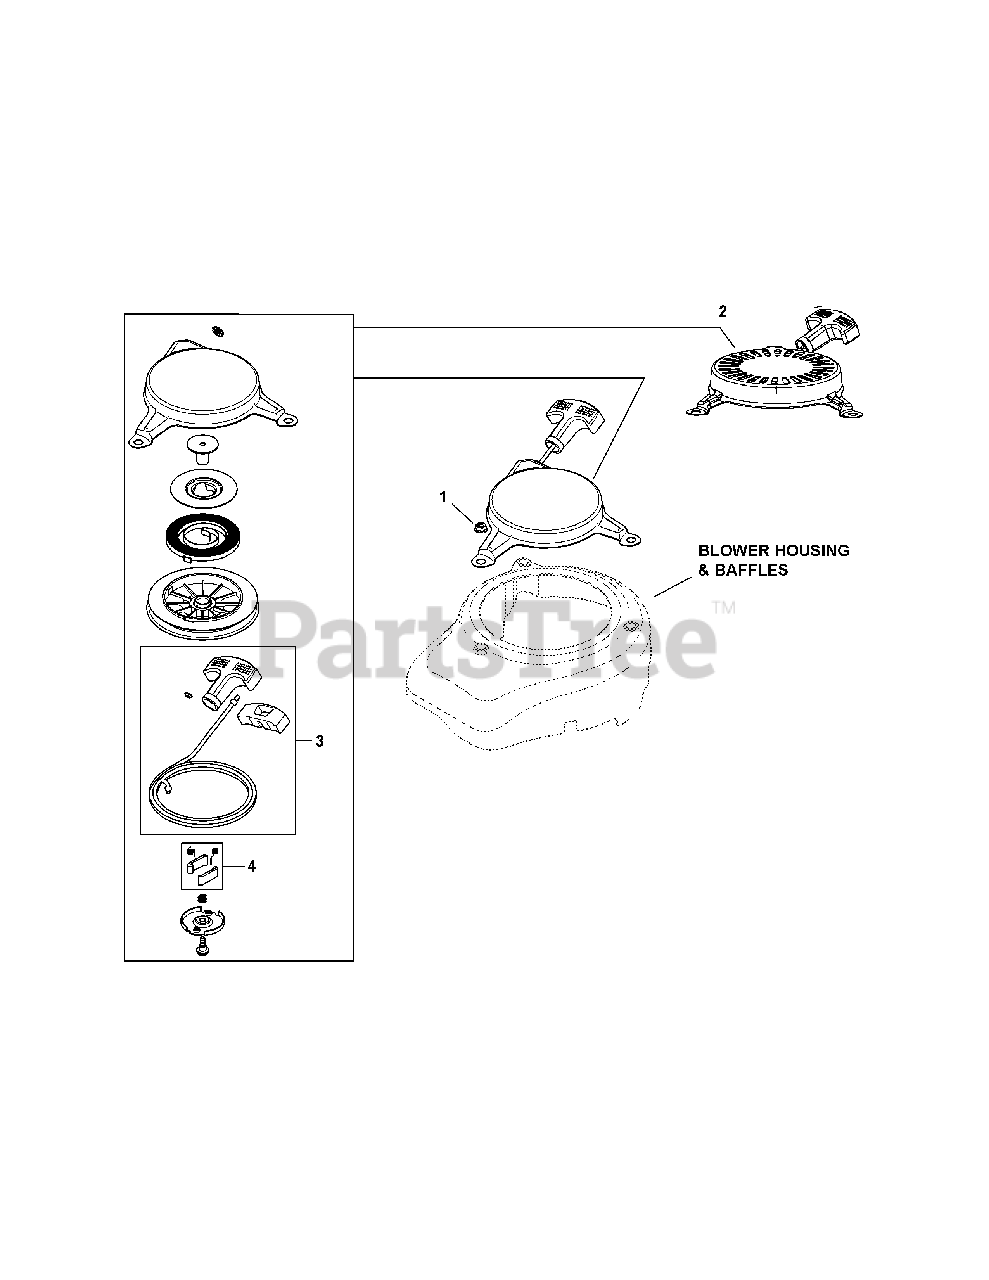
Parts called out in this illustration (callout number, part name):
1	Nut, Hex Flange, M6
2	Starter Assembly, Retractable
3	Recoil Starter Rope
4	Kit, Pawl Repair
